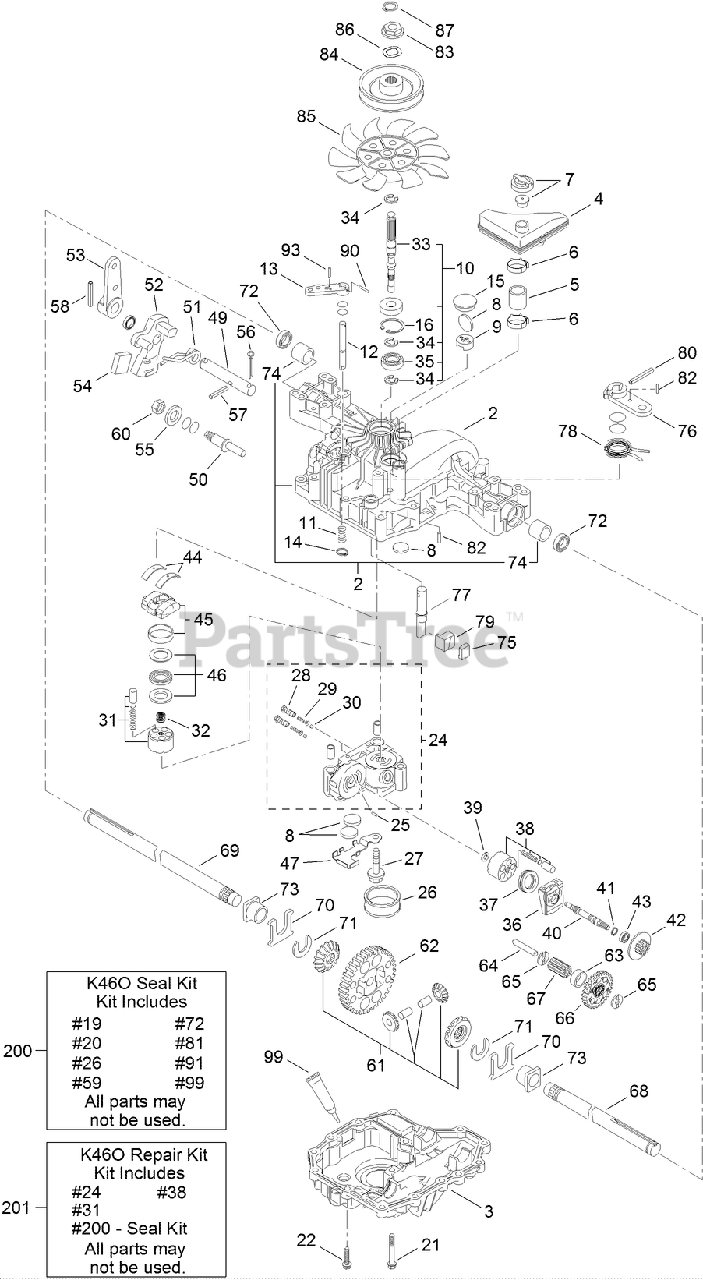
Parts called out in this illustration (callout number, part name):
2	UPPER CASE KIT
3	HOUSING-LOWER
4	TANK-RESERVOIR
6	CLAMP-MINIATURE
7	VALVE-VENT
8	MAGNET
9	HOLDER-MAGNET
10	PUMP SHAFT/BEARING KIT
11	SPRING
12	SHAFT-BYPASS
13	LEVER-BYPASS
15	PLUG-BORE
16	RING-SNAP
21	SCREW-TAPPING
22	SCREW-TAPPING
24	CENTER CASE W/BALL IDS KIT
26	FILTER
28	VALVE-IDS
29	SPRING-IDS
31	CYLINDER BLOCK (PUMP) KIT
32	SPRING-PUMP
33	SHAFT-PUMP
34	E-RING
35	BEARING
36	HOUSING
37	BEARING-THRUST
38	CYLINDER BLOCK KIT (MOTOR)
39	WASHER
40	SHAFT-MOTOR
41	RING-SNAP
42	MOTOR-GEAR
43	BEARING
44	METAL-THRUST
45	PLATE-SWASH
46	THRUST BEARING (PUMP) KIT
47	HOLDER-MAGNET
49	SHAFT-CONTROL
50	FULCRUM
51	SPRING-TORSION
52	ARM-CONTROL
53	LEVER-CONTROL
54	PLATE-JERKY
55	WASHER
56	PIN-COTTER
57	SPRING PIN
58	PIN-ROLL
61	DIFFERENTIAL GEAR KIT
62	GEAR-FINAL
63	COLLAR-PINION, FINAL
64	SHAFT-REDUCTION
65	WASHER
66	GEAR-REDUCTION
67	GEAR-PINION, FINAL
68	SHAFT-AXLE, LEFT
69	SHAFT-AXLE, RIGHT
70	WASHER-THRUST
71	RING
72	SEAL
73	BUSHING
74	BUSHING
75	SHOE-BRAKE
76	LEVER-BRAKE
77	SHAFT-BRAKE
78	SPRING-RETURN, BRAKE
79	ACTUATOR-BRAKE
82	PIN-SPRING
83	COLLAR-SPLINE
84	PULLEY
85	FAN-WHITE
86	WASHER-WAVE
87	RING-SNAP
90	PIN-SPRING
99	SEALANT
200	SEAL KIT
201	REPAIR KIT
